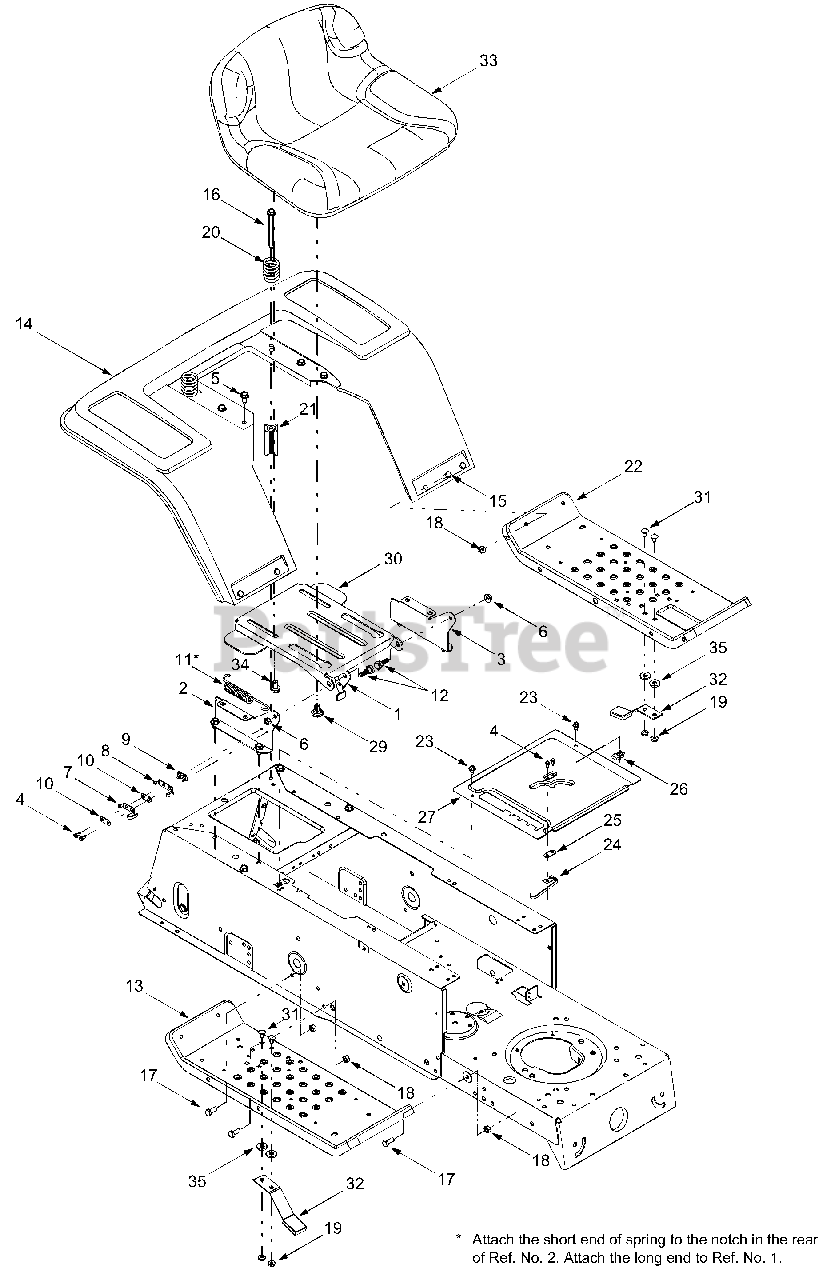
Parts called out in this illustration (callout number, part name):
1	Seat Lift Bracket
4	Self-tapping Screw, #8-18 x .50
5	Self-tapping Screw, 5/16-12 x .75
6	Hex Lock Nut, 5/16-18
7	Outer Seat Spring Switch
8	Inner Seat Spring Switch
9	Insulator Plate Boss
10	Insulator Plate
11	Extension Spring, .75 x 5.31
12	Shoulder Screw, .437 x .286
16	Self-tapping Screw, 5/16-18 x 3.5
17	Hex Screw, 5/16-18 x .75
18	Nylon Lock Nut, 5/16-18
19	Flange Lock Nut, 1/4-20
20	Compression Spring, 1.314 x 1.8
21	Spacer
24	Spring Switch, Long
25	Insulator Nut Plate
26	U-Clip Nut, 1/4-20
29	Shoulder Screw, .625 x .175, 3/8-16
31	Carriage Screw, 1/4-20 x .75
32	Blade Spindle Brake Assembly
33	Low Back Seat, Black
34	Screw, 3/8-16 x .625
35	Flat Washer, .344 x .750 x .120
